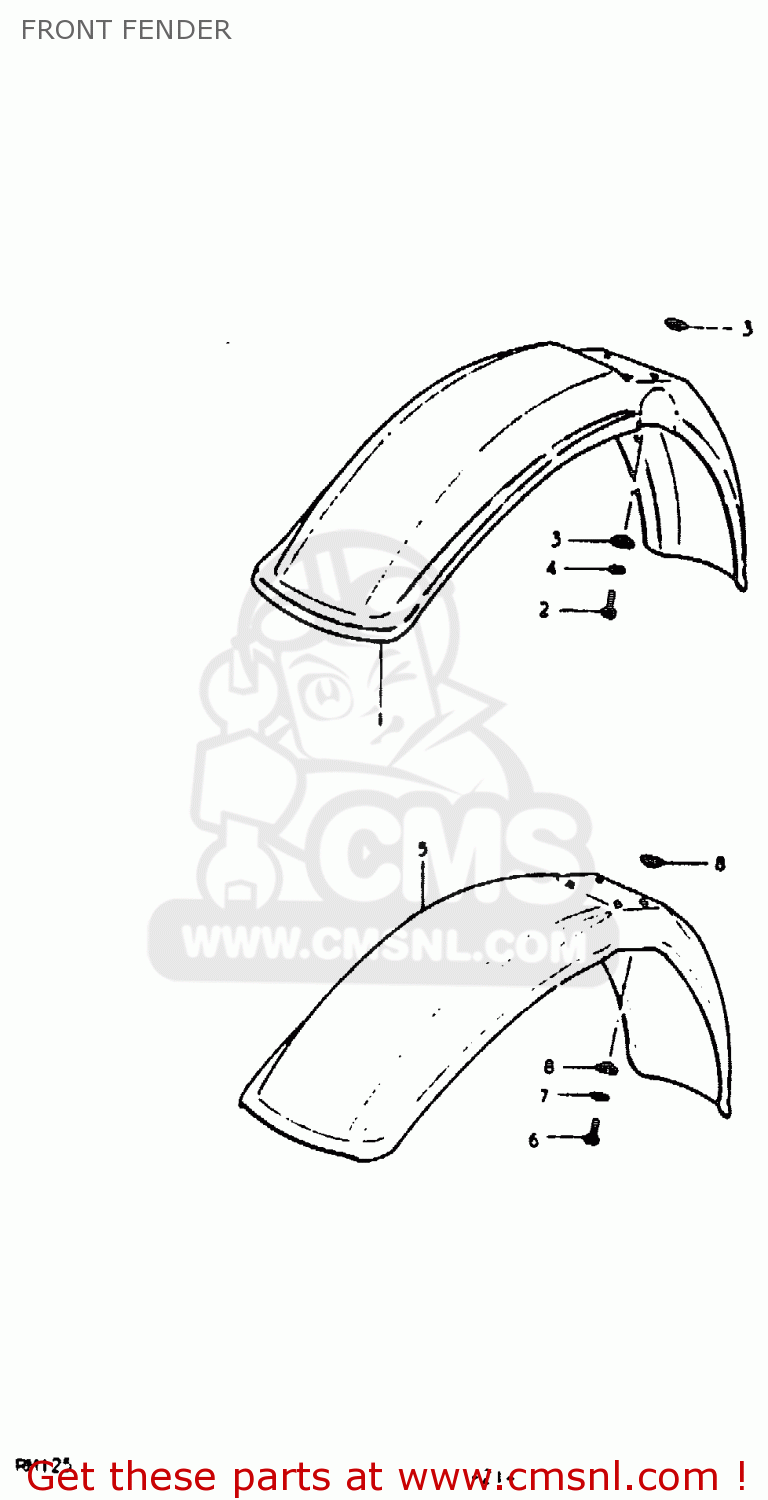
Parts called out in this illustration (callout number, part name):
5	FENDER,FRONT
6	BOLT, UPPER
7	LOCK WASHER
8	WASHER
